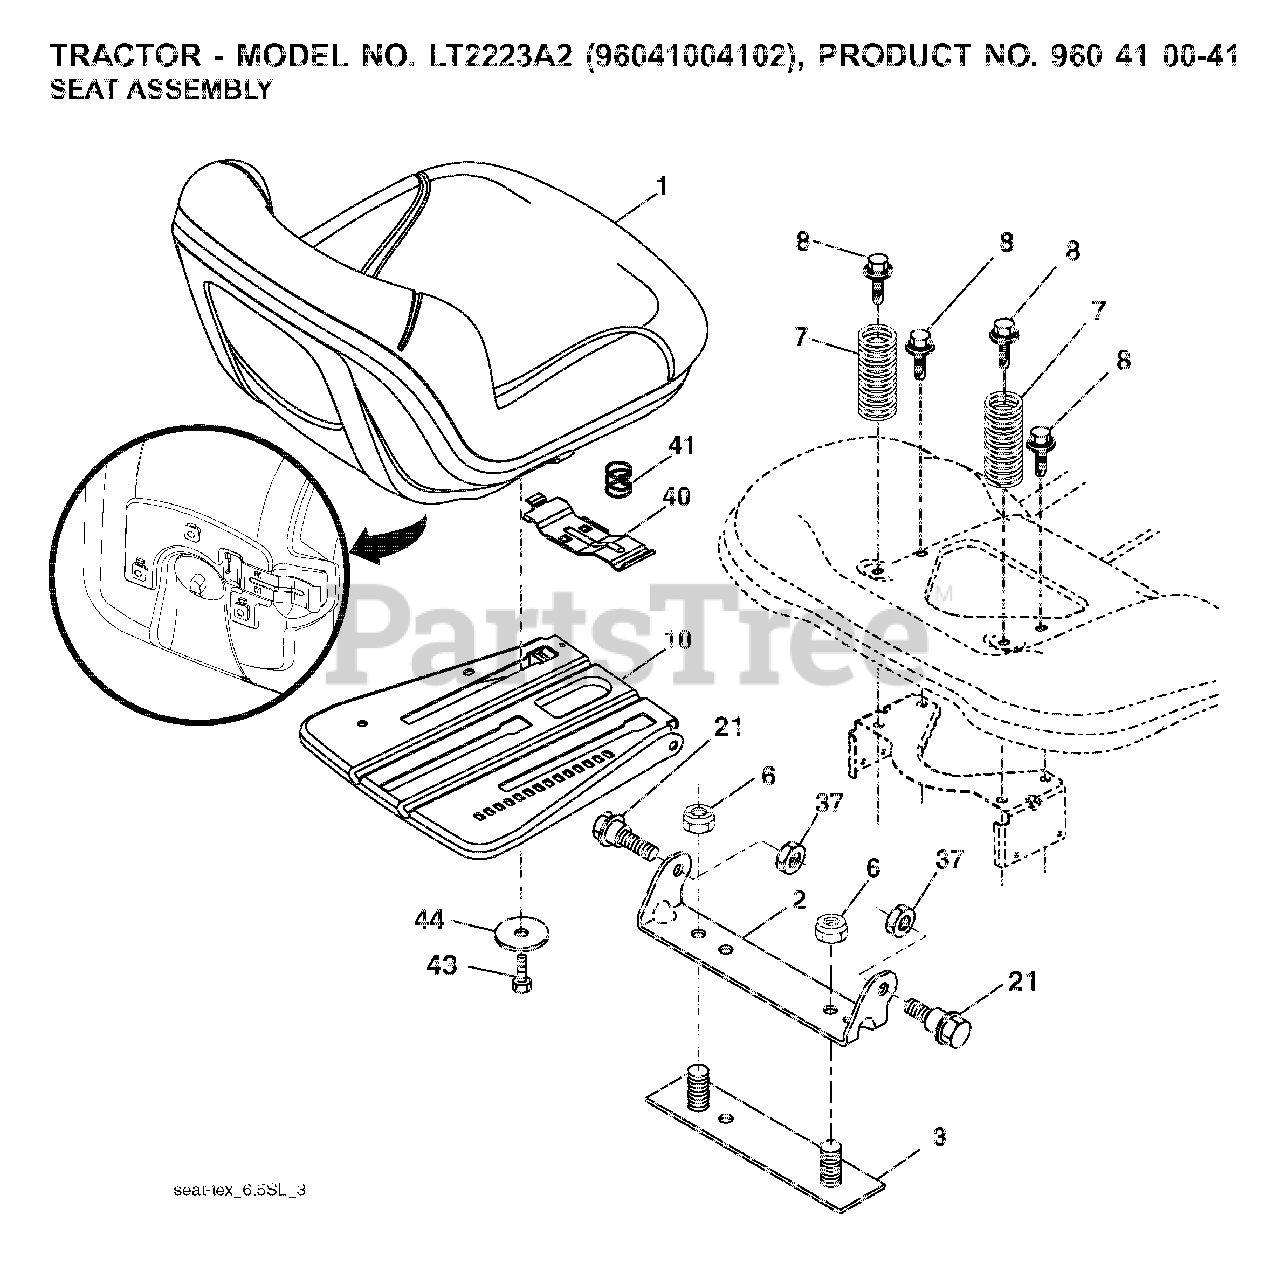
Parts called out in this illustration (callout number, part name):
1	SEAT.TG150.BLK.NLOGO.
2	BRKT.PIVOT.FENDER
6	NUT
7	SPRING COMPRESSION
8	BOLT, 5/16-18 X 1 3/4
10	PAN.ASM.SEAT.3PT
21	BOLT.SHOULDER.5/16-18
37	NUT.71038.31-18.HEX.NYLOCK
40	HANDLE.SLIDE.SEAT.TEX.BLACK
41	SPRING.LATCH.SEAT.TEX
44	WASHER 13/32 X 2-3/8 X 12GA
